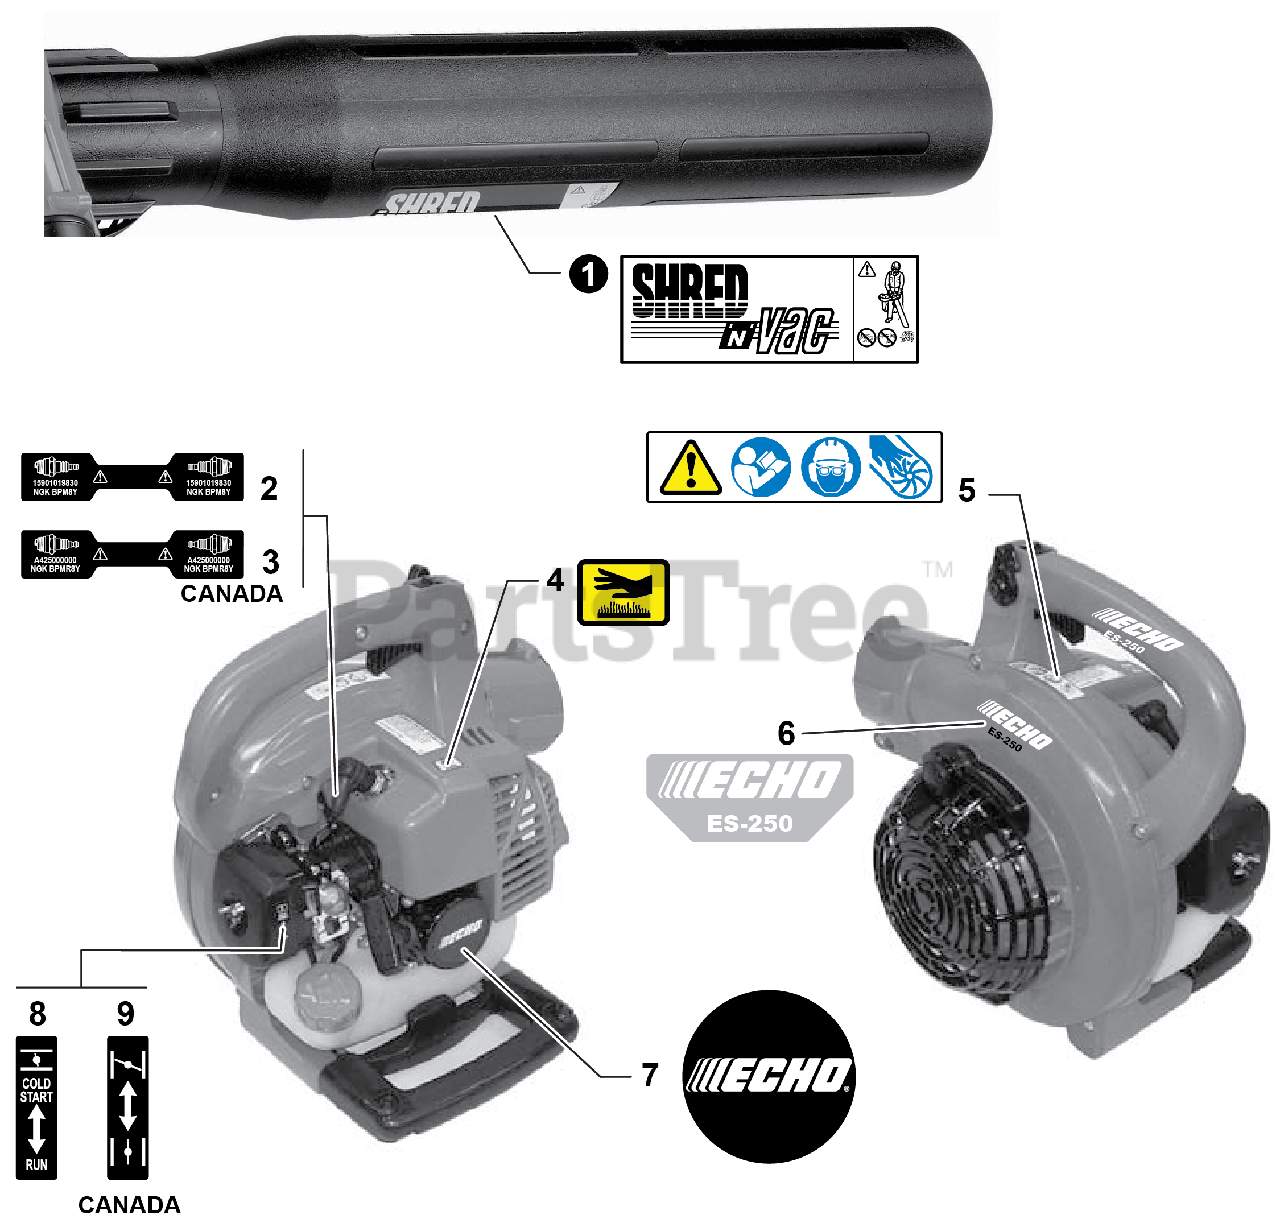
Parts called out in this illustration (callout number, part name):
1	LABEL, SHRED'N VAC
2	LABEL, SPARK PLUG - BPM8Y
3	LABEL, SPARK PLUG - BPMR8Y
4	LABEL, CAUTION - HOT
5	LABEL, CAUTION - ISO
6	LABEL, MODEL ES-250
7	LABEL, RECOIL STARTER
8	LABEL, CHOKE
9	LABEL, CHOKE
